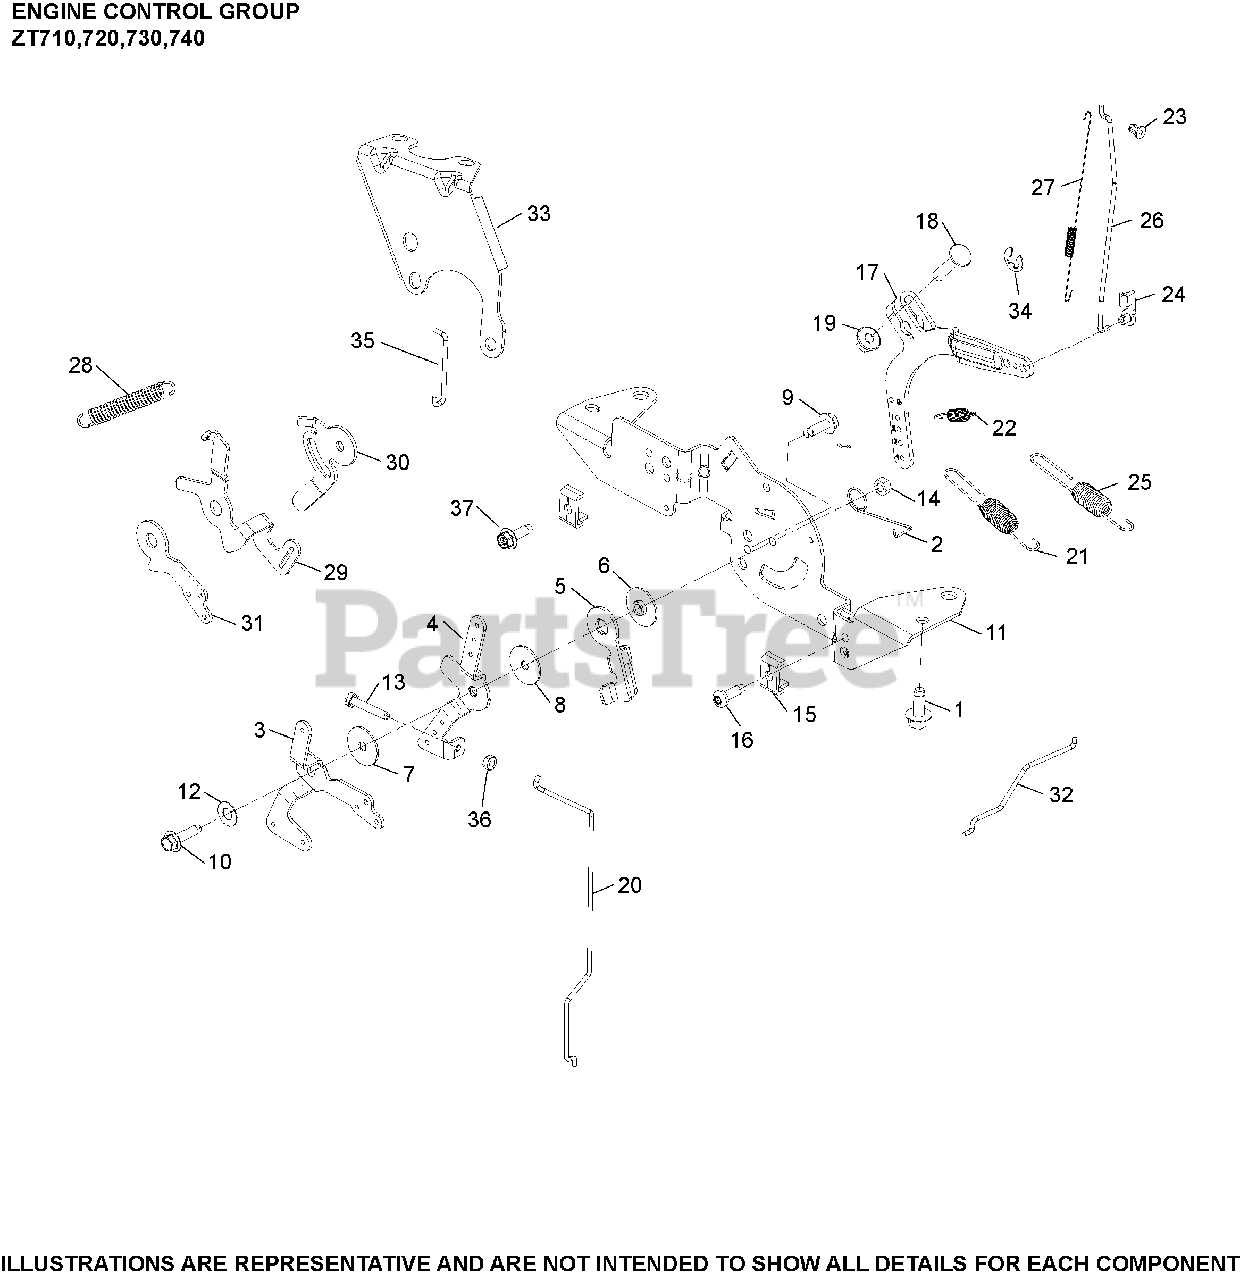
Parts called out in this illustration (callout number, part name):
1	SCREW, THREAD FORMING
2	SPRING, CHOKE RETURN
3	LEVER, CHOKE
4	LEVER, THROTTLE CONTROL
5	LEVER, THROTTLE ACTUATOR
6	SPACER, CONTROL ASSEMBLY
7	WASHER, FLAT 5.5 MM
8	WASHER, FLAT 5 MM
9	SCREW, THREAD FORMING
10	SCREW, THREAD FORMING - USE 25 086 473-S
11	BRACKET, CONTROL USE 32 126 18-s
12	WASHER, SPRING 1/4"
13	SCREW, SLT HD CAP M4X0.7X25
14	NUT, LOCK M5X.8
15	CLAMP, CABLE
17	LEVER, GOVERNOR - (#2409069S)
18	BOLT, RD HD SQ NECK M6X1.0X25
19	NUT, FLG M6X1.0
20	LINKAGE, CHOKE
22	SPRING, GOVERNED IDLE
23	BUSHING, LINKAGE RETAINING
24	BUSHING, THROTTLE LINKAGE
25	SPRING, GOVERNOR (ORANGE)
27	SPRING, LINKAGE USE 32 089 11-S
32	LINKAGE, THROTTLE USE 24 079 04-S
34	CLIP, RETAINER GOVERNOR SHAFT
36	NUT, M4X0.7
37	SCREW, THREAD FORMING
